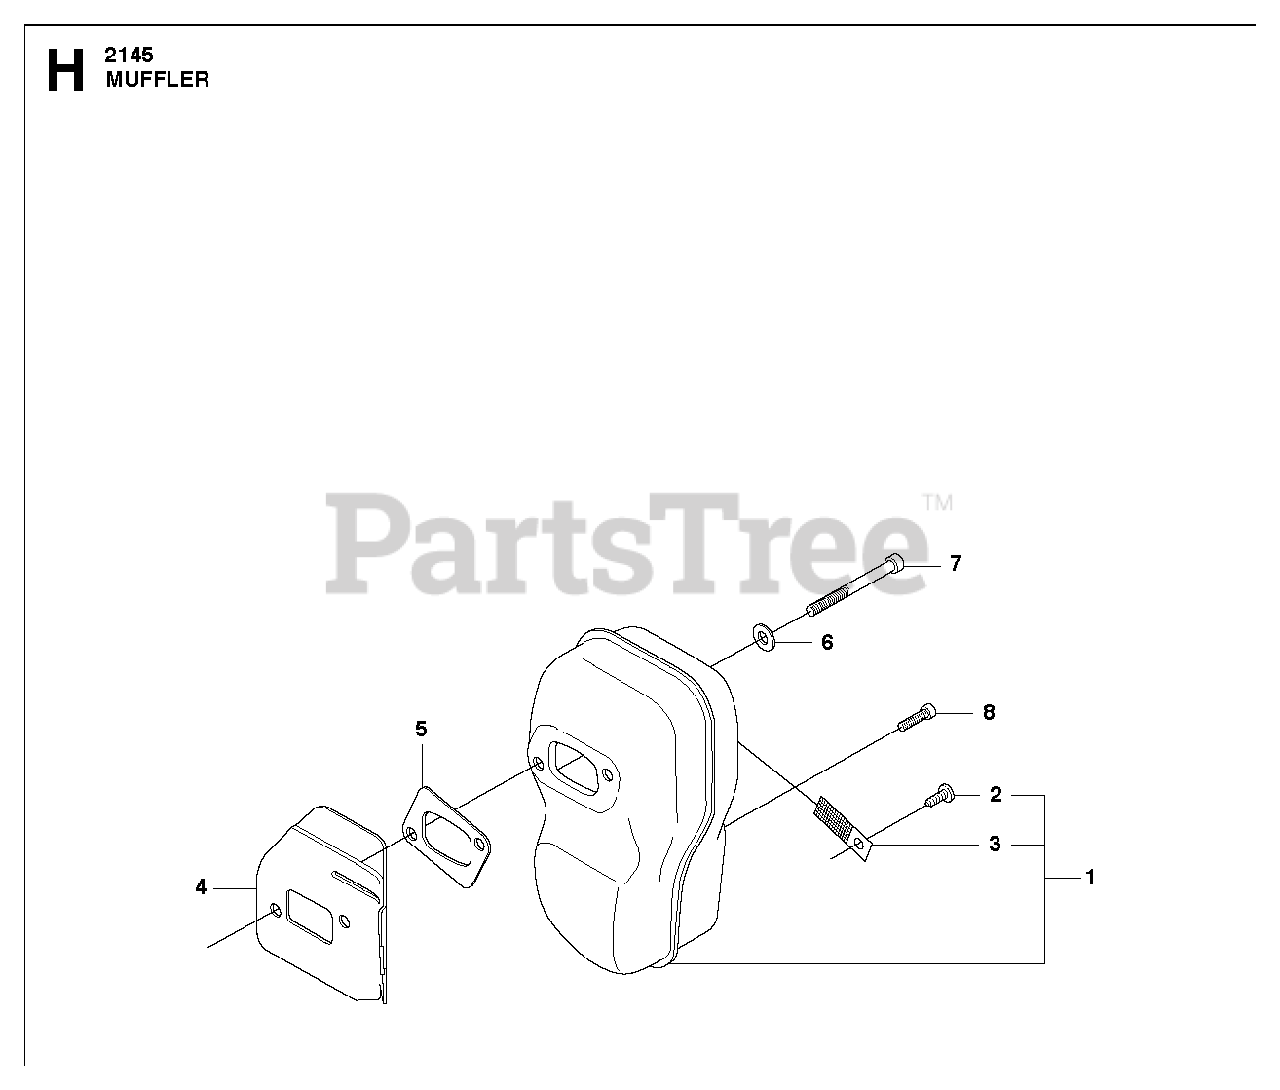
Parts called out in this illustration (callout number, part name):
1	MUFFLER
2	SCREW
3	SCREEN
4	DEFLECTOR
6	DOUBLE WASHER
8	SCREW IHSCFM
